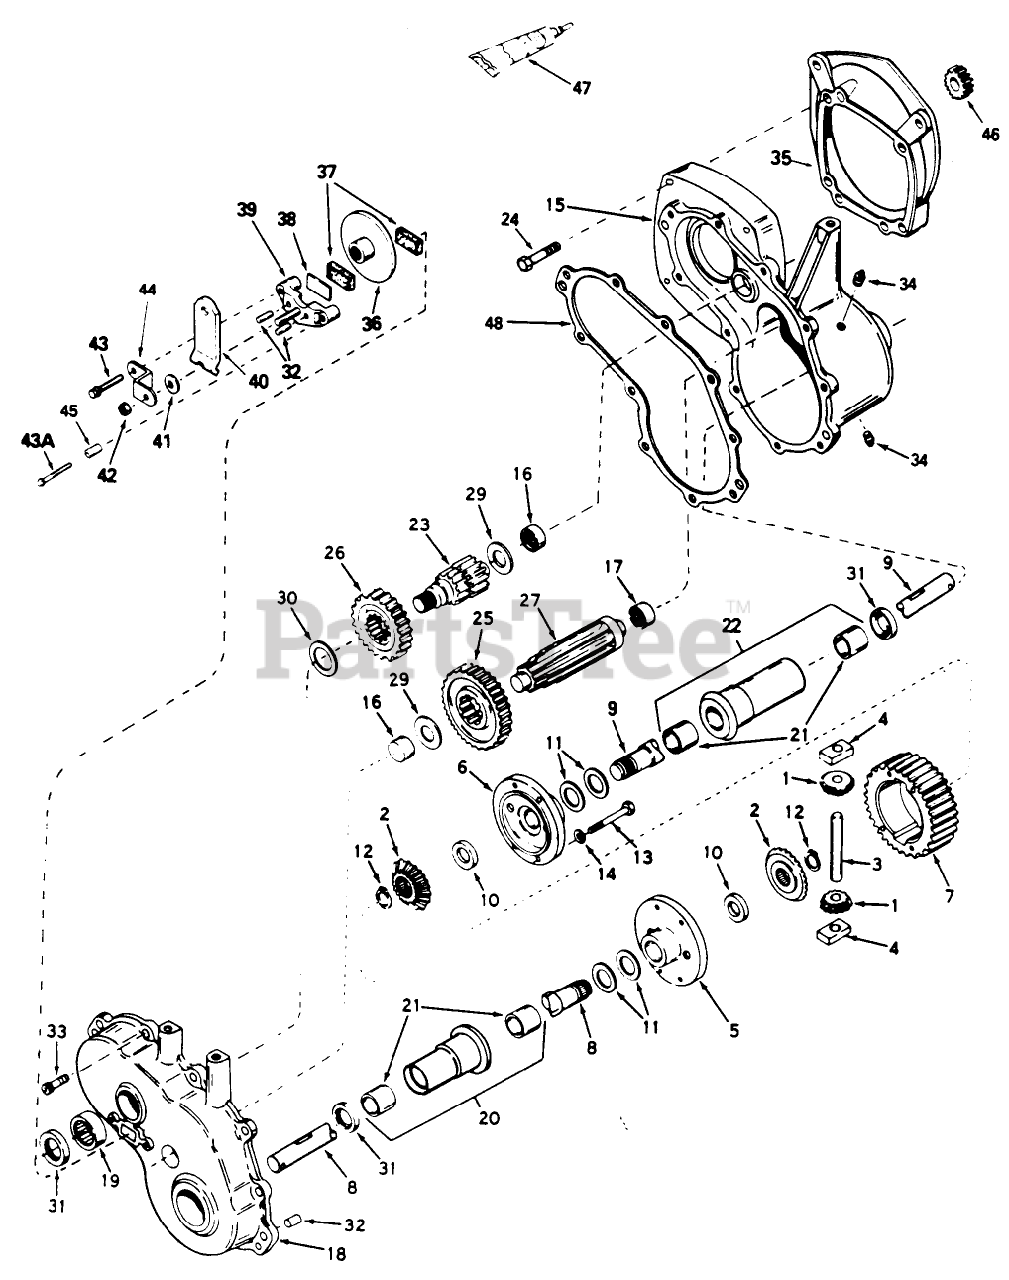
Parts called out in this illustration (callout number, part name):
1	Pinion-Bevel
2	Gear-Bevel
3	Pin-Drive
4	Biock-Drive
5	Carrier-Differential
6	Carrier-Differential
7	Gear-Ring
8	Axle-16-5/8"
9	Axle-21-57/64"
10	Washer
11	Washer
12	Ring-Snap
13	Screw-Hex Hd.
14	Lockwasher
15	Case Assembly (Incl. Ref. #16 & 17)
16	Bearing
17	Bearing-Needle
18	Cover Assembly (Incl. Ref. #16 & 19)
19	Bearing Needle
20	Housing Assembly-6-5/8" (Incl. Ref. #21)
21	Bushing
22	Housing Assembly-8-5/8" (Incl. Ref. #21)
23	Shaft-Brake
24	Screw-Hex Hd.
25	Gear-Output
26	Gear-Spur
27	Shaft-Output
29	Washer
30	Washer
31	Seal-Oil
32	Dowel Pin
33	Screw-Thread Forming
34	Plug-Pipe
35	Plate-Adapter
36	Disc-Brake
37	Pad-Brake (Pack of 2)
38	Brake Pad Plate
39	Nozzle-Carburetor
40	Lever-Brake
41	Washer
42	Locknut
43	Screw
43A	Screw-Thread Forming
44	Bracket
45	Spacer
46	Gear-Spur 22T
47	Gasket Eliminator
48	Gasket
